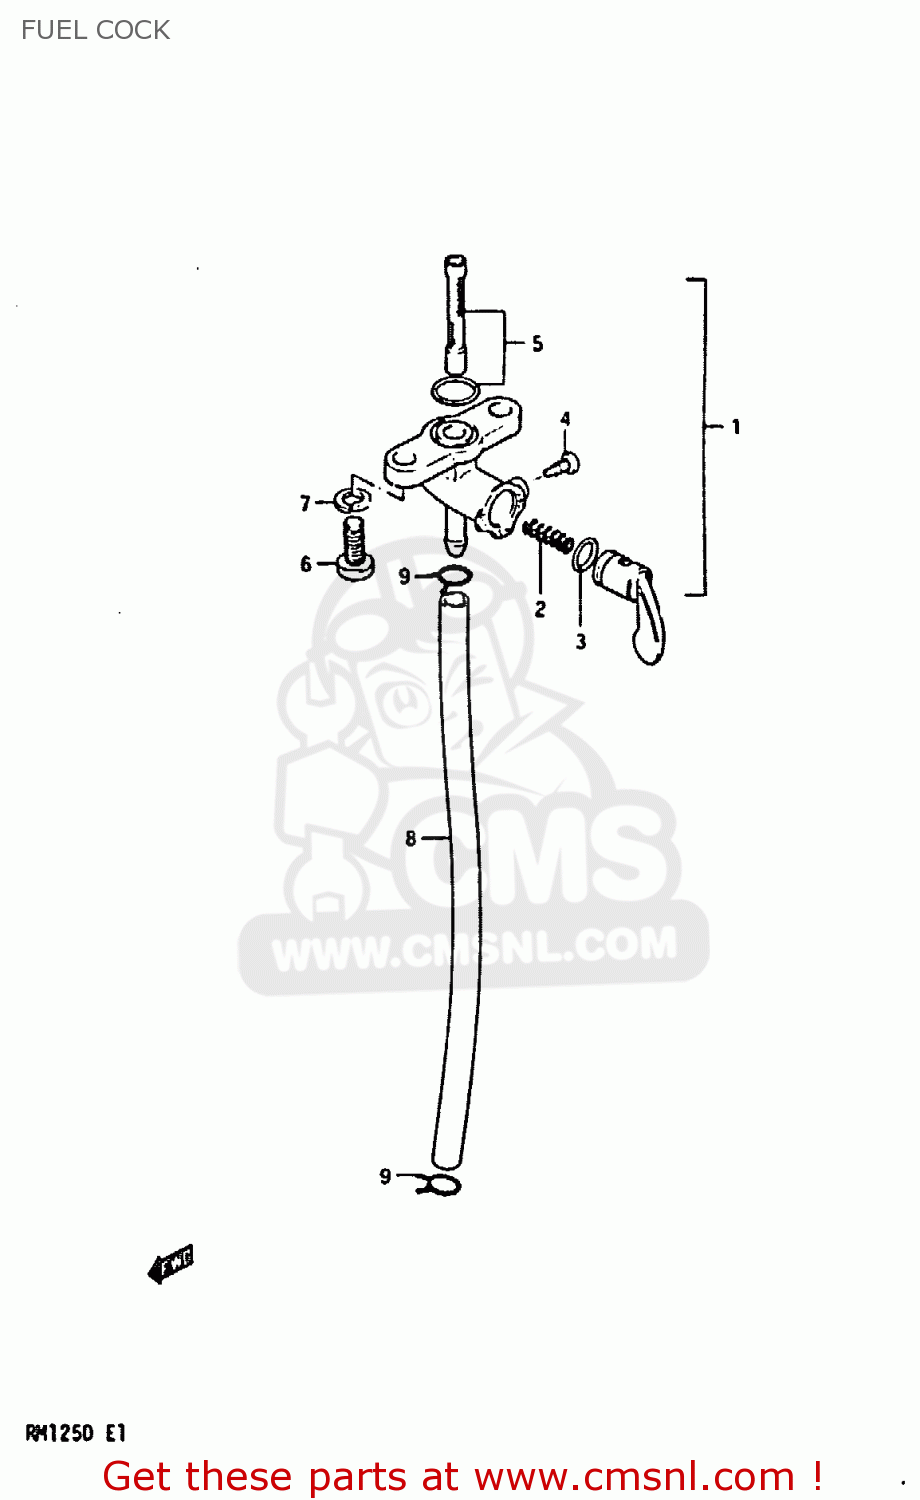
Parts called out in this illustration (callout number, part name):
1	COCK ASSEMBLY,FUEL
2	SPRING,FUEL COCK VALUE
3	O RING,LEVER
4	SCREW
5	FILTER SET FUEL
6	SCREW
7	LOCK WASHER
8	HOSE
9	CLIP
